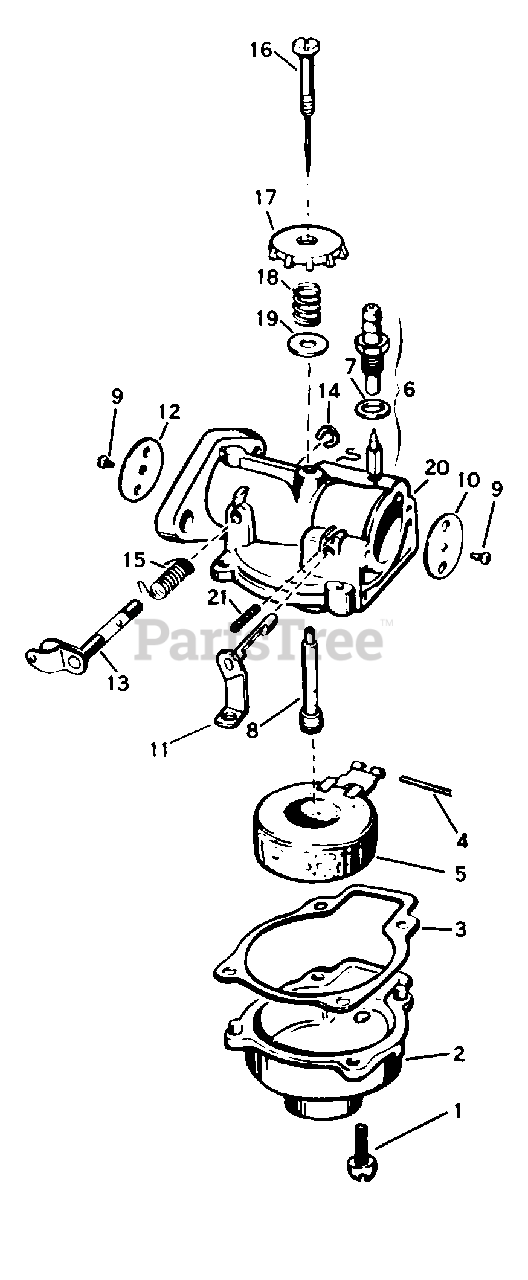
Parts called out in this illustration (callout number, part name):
1	Screw-Float Bowl to Carb.
2	Float Chamber
3	Gasket-Carburetor Body to Float Chamber
4	Hinge Pin-Float Arm
5	Float and Arm Assembly
6	Float Valve and Seat Assembly
7	Washer-Float Valve Seat
8	Nozzle
9	Screw-Choke and Throttle Disc
10	Disc-Choke
11	Choke Shaft-Lever Assembly
12	Disc-Throttle
13	Throttle Shaft and Ring Assy.
14	Grip Ring
15	Spring-Throttle Shaft
16	Needle Assembly
17	Adjusting Knob-Needle Valve
18	Spring-Needle Adjustment
19	Washer-Needle Adjustment
20	Carburetor Body and Spring Assy.
21	Spring-Choke Lever
